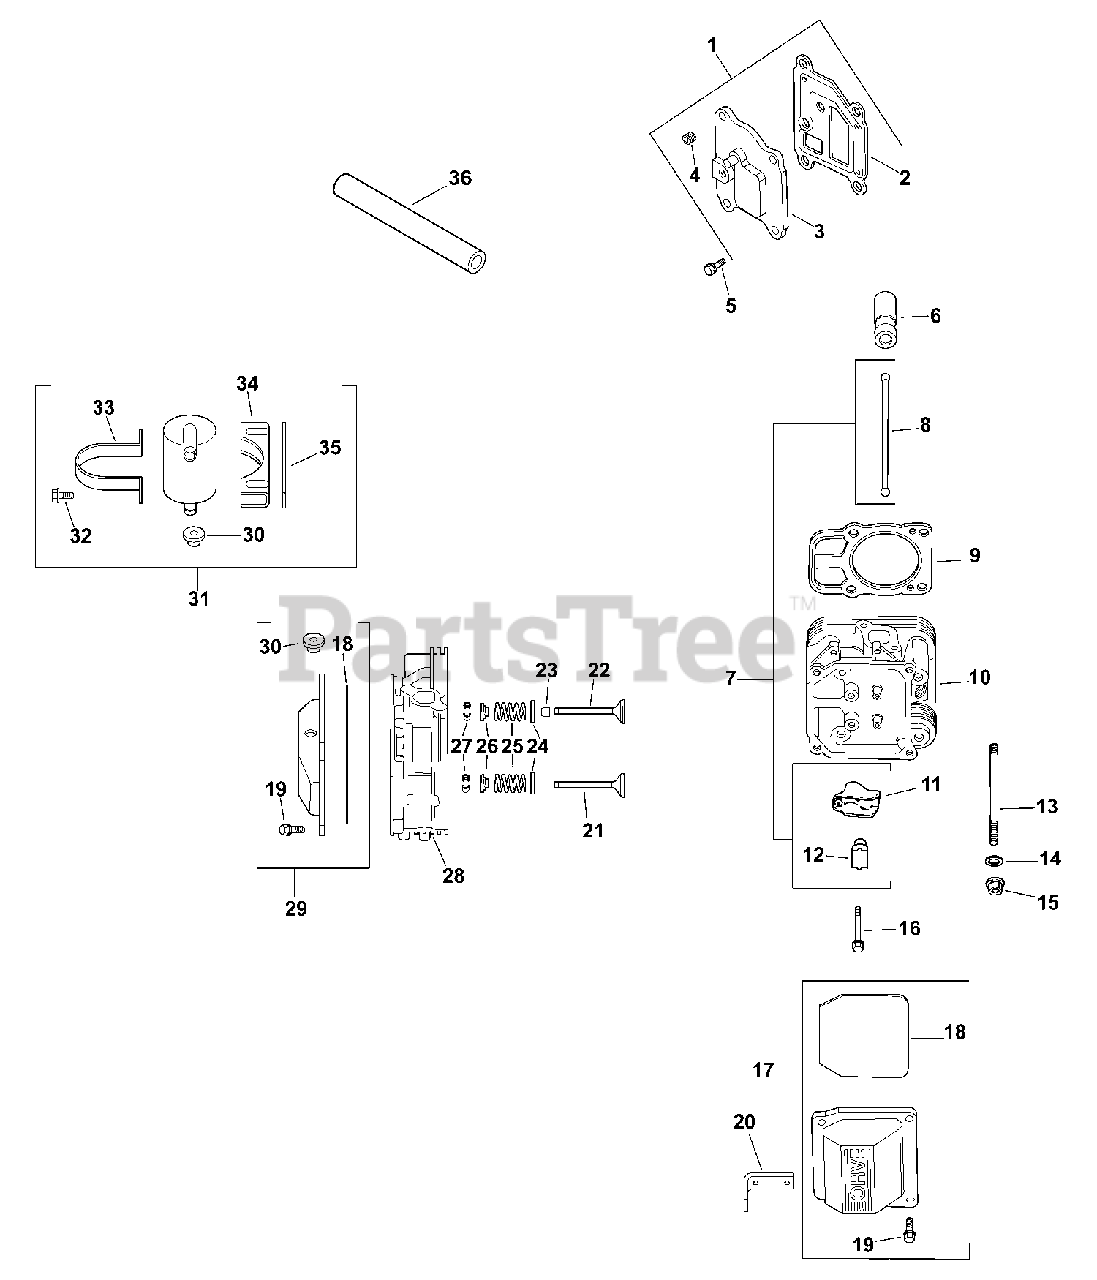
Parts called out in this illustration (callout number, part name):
1	KIT, BREATHER COVER W/GASKET
3	COVER, BREATHER -USE 24 096 125-S
4	PLUG, CTSK PIPE 1/8"
5	SCREW,FLG THD FRM M6X1.0X20-(#25086396S)
6	LIFTER, HYDRAULIC VALVE-USE 25 351 10-S
7	KIT, VALVE TRAIN
8	ROD, PUSH
9	CYL HEAD GASKET KIT-USE 24 841 04-S
10	HEAD, ASSEM CYLINDER #2 -USE 24 318 116-
11	ARM, ROCKER
12	PIVOT, CYLINDRICAL ROCKER ARM-USE 24 599
13	STUD, M8X1.25
14	WASHER, FLAT 8.6 MM
15	NUT, FLG M8X1.25
16	SCREW, ROCKER ARM PIVOT-USE M-640034-S
17	KIT, VALVE COVER-PLAIN
18	O-RING (YELLOW) -USE 24 153 30-S
19	SCREW, FLG M6X1.0X30
20	STRAP, LIFTING-USE 25 445 03-S
21	VALVE, EXHAUST (STD) - USE 32 016 01-S
22	VALVE, INTAKE (STD)
23	SEAL, VALVE STEM - (#2503214S)
24	RETAINER, SPRING
25	SPRING, VALVE
26	RETAINER, VALVE SPRING - USE 25 173 28-S
27	KIT, RETAINER
28	HEAD, ASSEM CYLINDER #1 -USE 24 318 108-
29	KIT, VALVE COVER
30	GROMMET, RUBBER
31	KIT, BREATHR SEPARATR-(#24755241S)
32	SCREW,FLG THD FRM M5X0.8X16-(#25086398S)
33	STRAP, BREATHER - USE 24 755 241-S
34	BRACKET, BREATHER SEPARATOR
35	SPACER
36	HOSE, BREATHER-USE 24 326 93-S
2401602-S	VALVE, EXHAUST (.25)
2401702-S	VALVE, INTAKE (.25)
